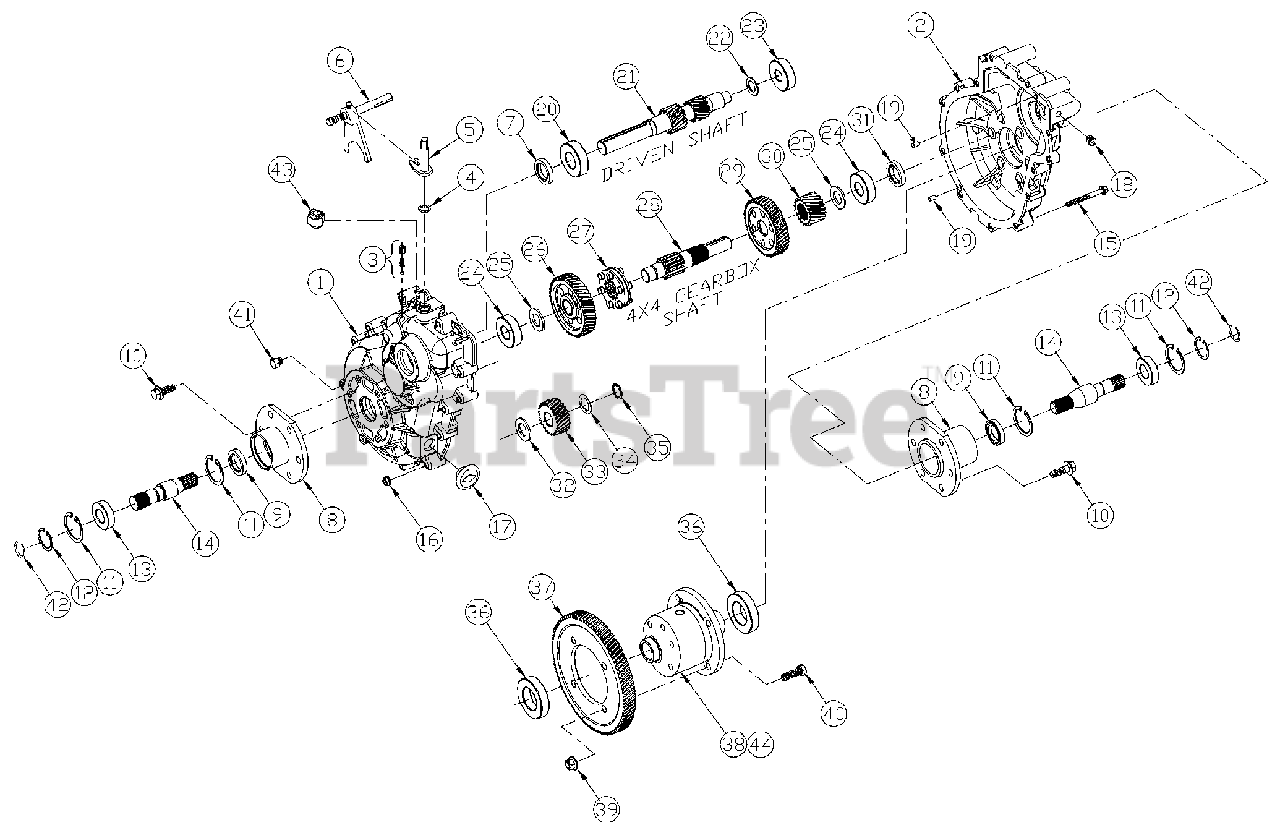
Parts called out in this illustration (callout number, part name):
1	DANA HOUSING AND SHAFT ASSBLY
2	DANA HOUSING-AXLE FIN
3	DANA KIT, DETENT
4	DANA SEAL - OIL
5	DANA ACTUATOR ASSY
6	DANA SHIFT ROD SUB-ASSY
7	DANA SEAL - OIL
8	REAR TUBE ASSY
9	SEAL - OIL
10	DANA SCREW - FLG HEAD
11	DANA RING, RETAINING
12	RING - RETAINER
13	BEARING - BALL SINGLE
14	SHAFT - AXLE, FIN
15	DANA SCREW - FLG HEAD
16	DANA NUT - LOCK
17	DANA PLUG - RUBBER
18	DANA VENT PLUG
19	DANA PIN - DOWEL
20	DANA BEARING 6205
21	DANA SHAFT - INPUT FIN
22	DANA KIT, SHIM
23	DANA BEARING -6303 BALL SINGLE
24	DANA BEARING -6204 BALL SINGLE
25	DANA SPACER - FLAT
26	DANA GEAR ASSY - FORWARD
27	DANA GEAR - CLUTCH
28	DANA SHAFT - INTERMEDIATE FIN
29	DANA GEAR ASSY - REVERSE
30	DANA GEAR - HELICAL FIN
31	DANA SEAL - OIL
32	DANA WASHER - THRUST
33	DANA GEAR ASSY - IDLER
34	DANA WASHER - THRUST
35	DANA RING - SNAP
36	DANA BEARING 6007
37	DANA GEAR - HELICAL FIN
38	DIFFERENTIAL, AUTO-LOCK
39	DANA NUT - LOCK
40	DANA BOLT - HEX
41	DANA DRAIN PLUG
42	RETAINER - SHAFT, AXLE
43	SWITCH, NEUTRAL, DANA GBOX Kit includes 1 ea. #38, 4 ea. #39 & 4 ea. #40
44	AUTO-LOK KIT*
